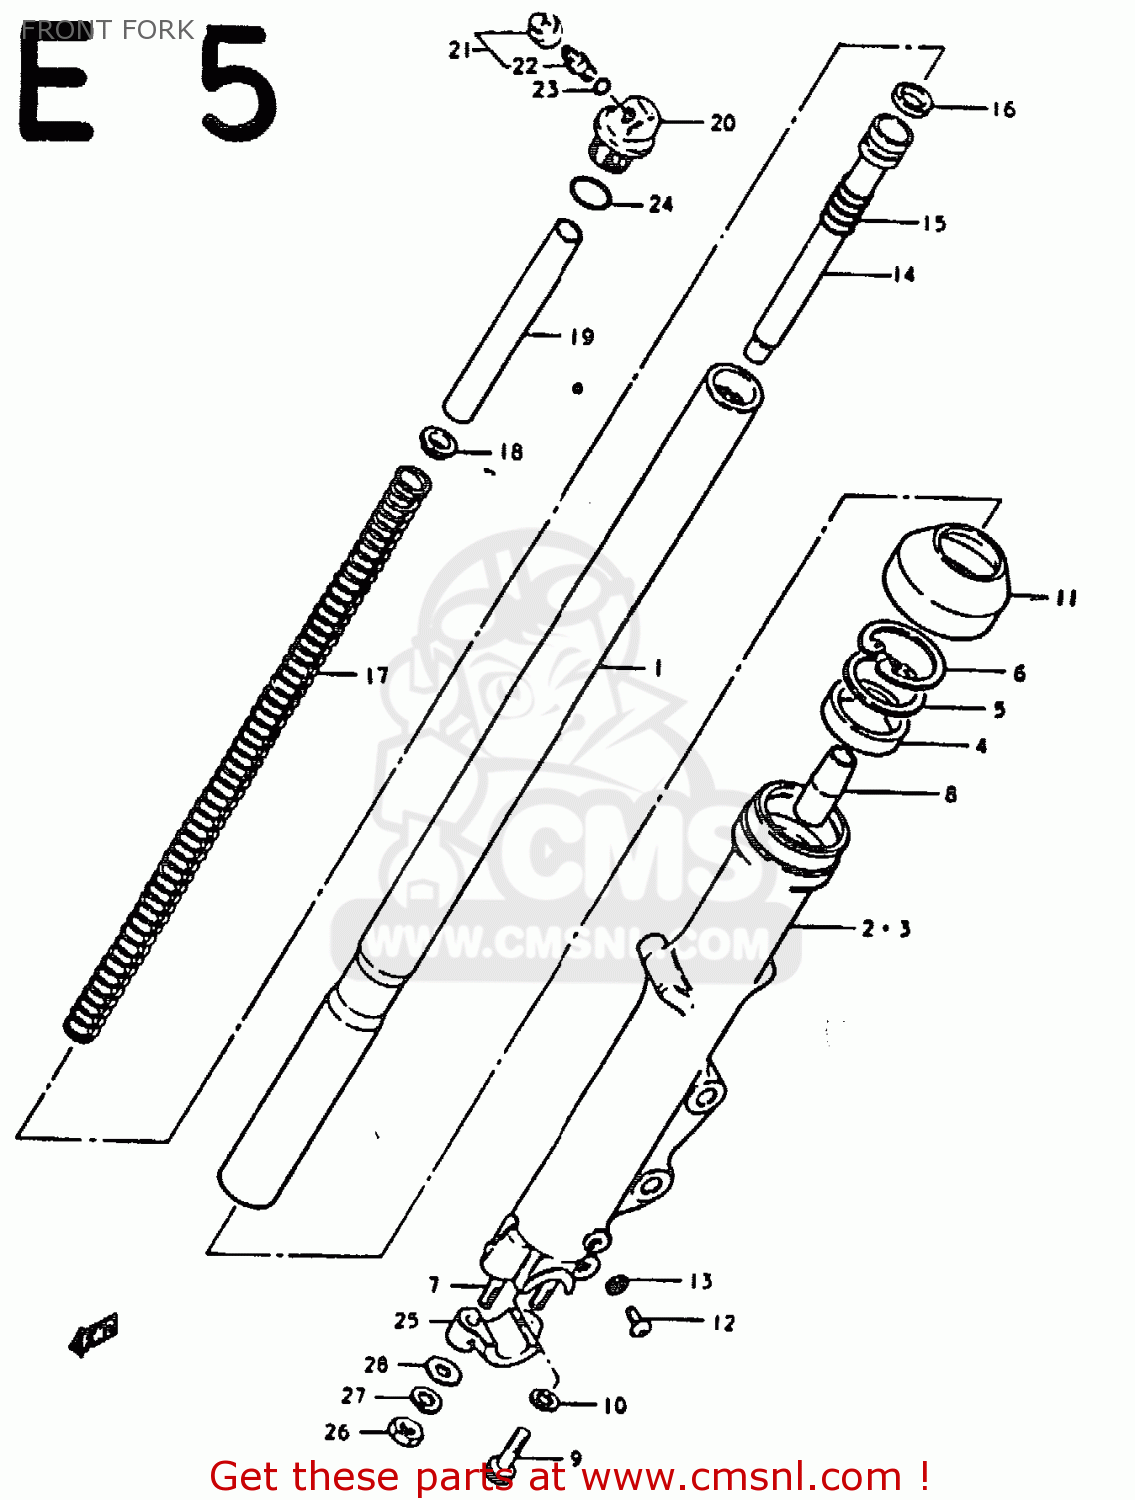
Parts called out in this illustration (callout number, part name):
1	TUBE,FORK,INNER
2	TUBE,FORK,OUTER,RIGHT
3	TUBE,OUTER,LEFT
4	OIL SEAL,FRONT FORK
5	WASHER. FRONT FORK
6	CIRCLIP,FORK OIL SEAL
7	STUD BOLT
8	PIECE,OIL LOCK
9	BOLT,FORK CYLINDER(10X25)
10	GASKET (NAS)
11	SEAL,DUST
12	SCREW
13	GASKET,DRAIN,PLUG (NAS)
14	CYLINDER,FRONT FORK
15	SPRING,REBOUND
16	RING,PISTON
17	SPRING,FRONT FORK
18	GUIDE,FRONT FORK SPRING C
19	SPACER,FRONT FORK SPRING
20	CAP
21	VALVE & CAP ASSY
22	VALVE
23	O RING
24	O RING
25	HOLDER,AXLE
26	NUT (8MM)
27	LOCK WASHER
28	WASHER
